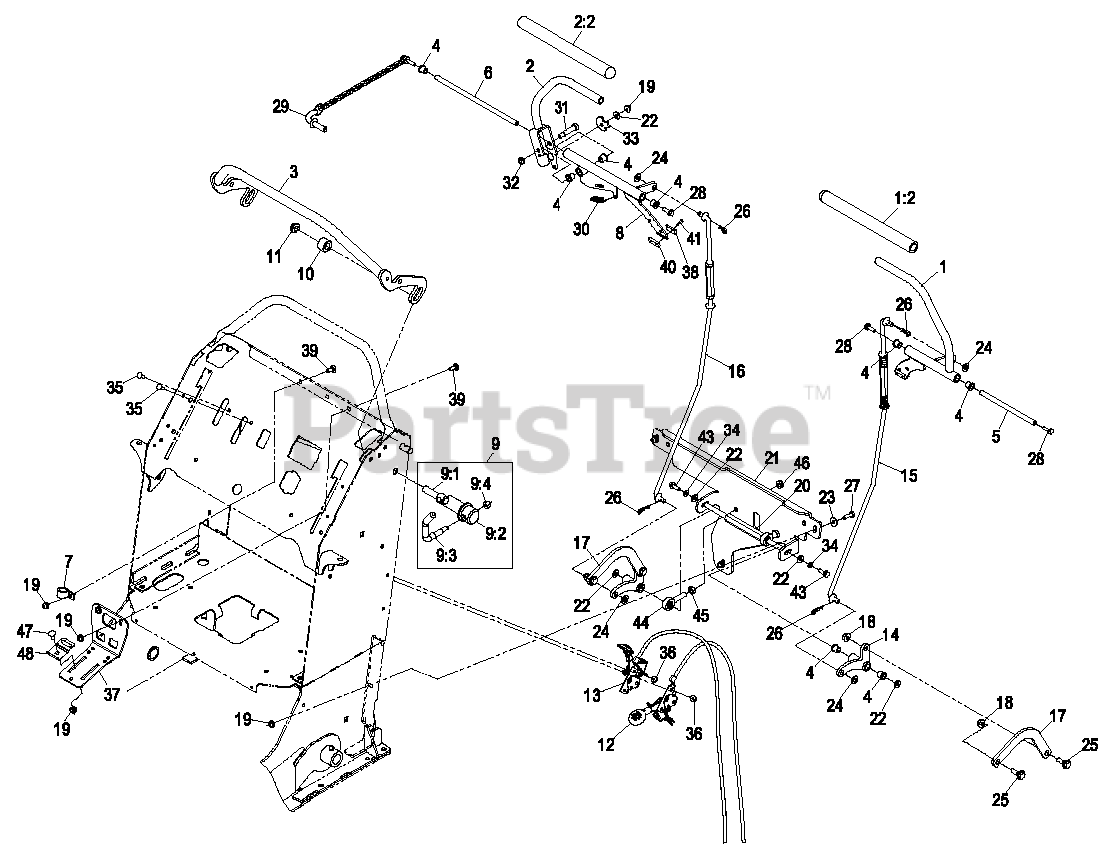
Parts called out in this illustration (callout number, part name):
1	LEVER ASM, LH
1:2	GRIP-HANDLE, CONTROL
2	LEVER ASM, RH
2:2	GRIP-HANDLE, CONTROL
4	BEARING
5	SHAFT-PIVOT
7	CLAMP-CABLE
8	CONTROL,MOTION ASM RH
9	LEVER ASM
9:1	SCREW-LOCK
9:2	CAP-LOCK
9:4	NUT-LOCK, NI
10	SPACER-CLAMP
11	NUT-HEX
14	LEVER-BELLCRANK, MOTION
15	LINKAGE-TRACKING CONTROL,
16	LINKAGE-MOTION CONTROL, R
17	LINK-BELLCRANK, PUMP
18	NUT-HF, NI
20	SHAFT-BELLCRANK PIVOT
21	BRACKET-BELLCRANK
22	WASHER-FLAT
23	WASHER-FLAT
24	WASHER-PLAIN
25	SCREW-SHOULDER
26	PIN-COTTER
27	SCREW-HH
28	SCREW-HHF
29	HOC PIN ASM
30	SPRING-EXTENSION
31	SCREW-HSH
32	NUT-LOCK, NI
33	CAM-LEVER
34	SCREW-HH
35	BOLT-CARR
37	BRACKET, REED SWITCH
38	ACTUATOR-SWITCH, REED
39	BOLT-CARR
40	PLATE-TAPPED
41	SCREW-HH
43	SCREW-HHF
44	BALLJOINT
45	NUT-HJ
46	NUT-HEX
47	SCREW-CARR
48	CLAMP, REED SWITCH
